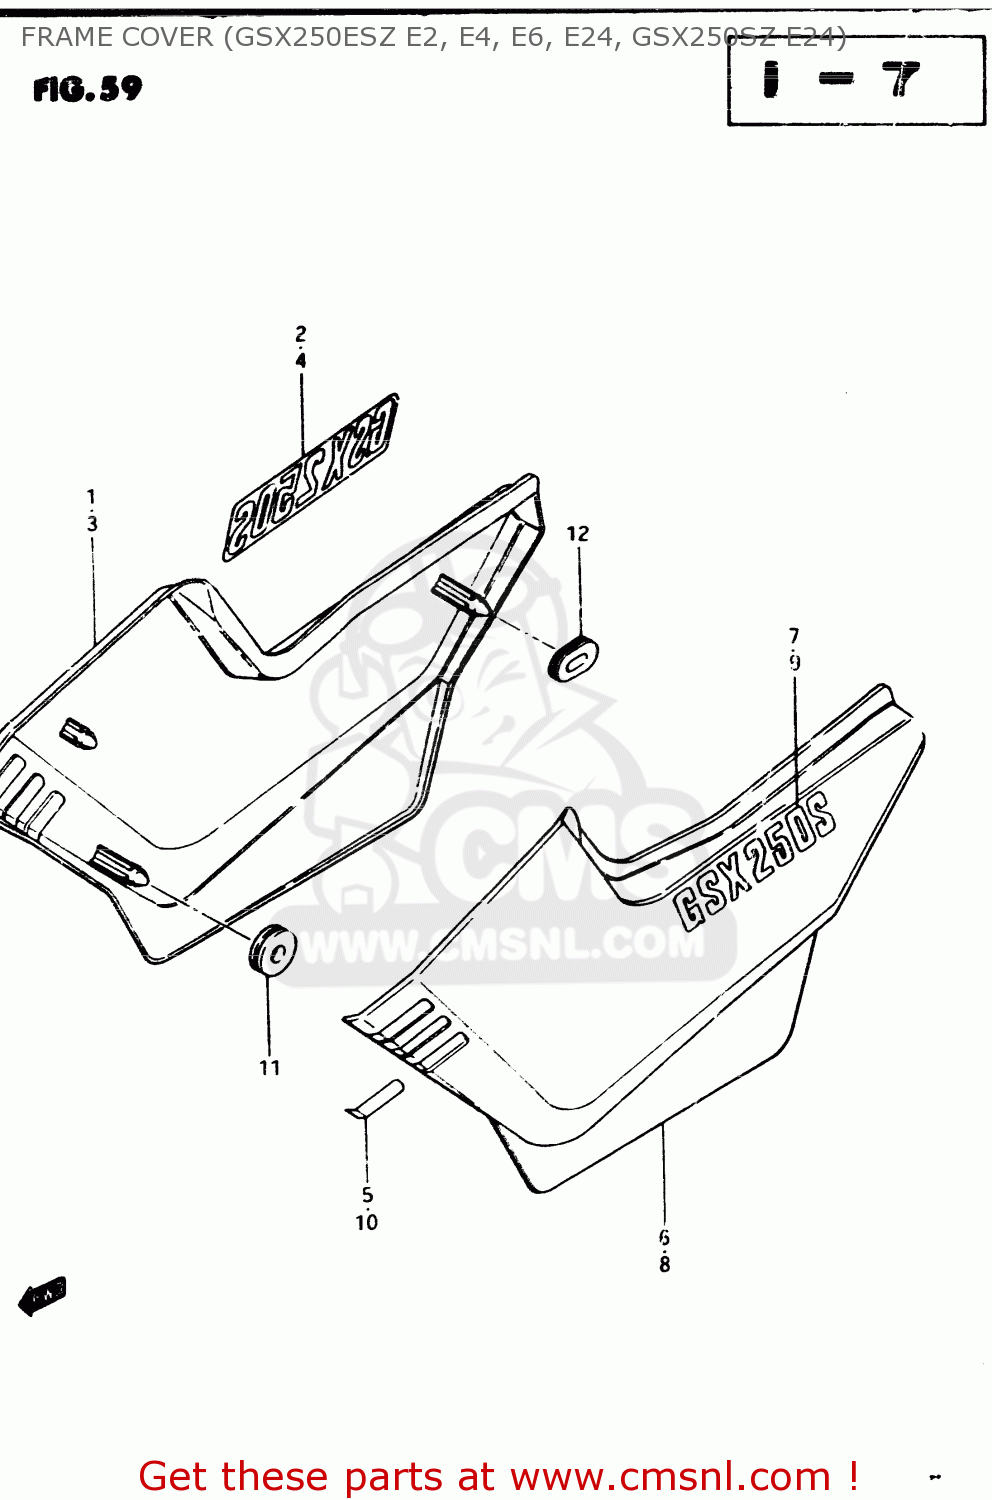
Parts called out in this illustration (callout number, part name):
1	COVER, FRAME RH (RED)
2	EMBLEM, LH
3	COVER, FRAME RH (SILVER)
4	EMBLEM, LH
5	LABEL,FRAME COVER DENT
6	COVER, FRAME LH (RED)
7	EMBLEM, LH
8	COVER, FRAME LH (SILVER)
9	EMBLEM, LH
10	LABEL,FRAME COVER
11	CUSHION
12	CUSHION
